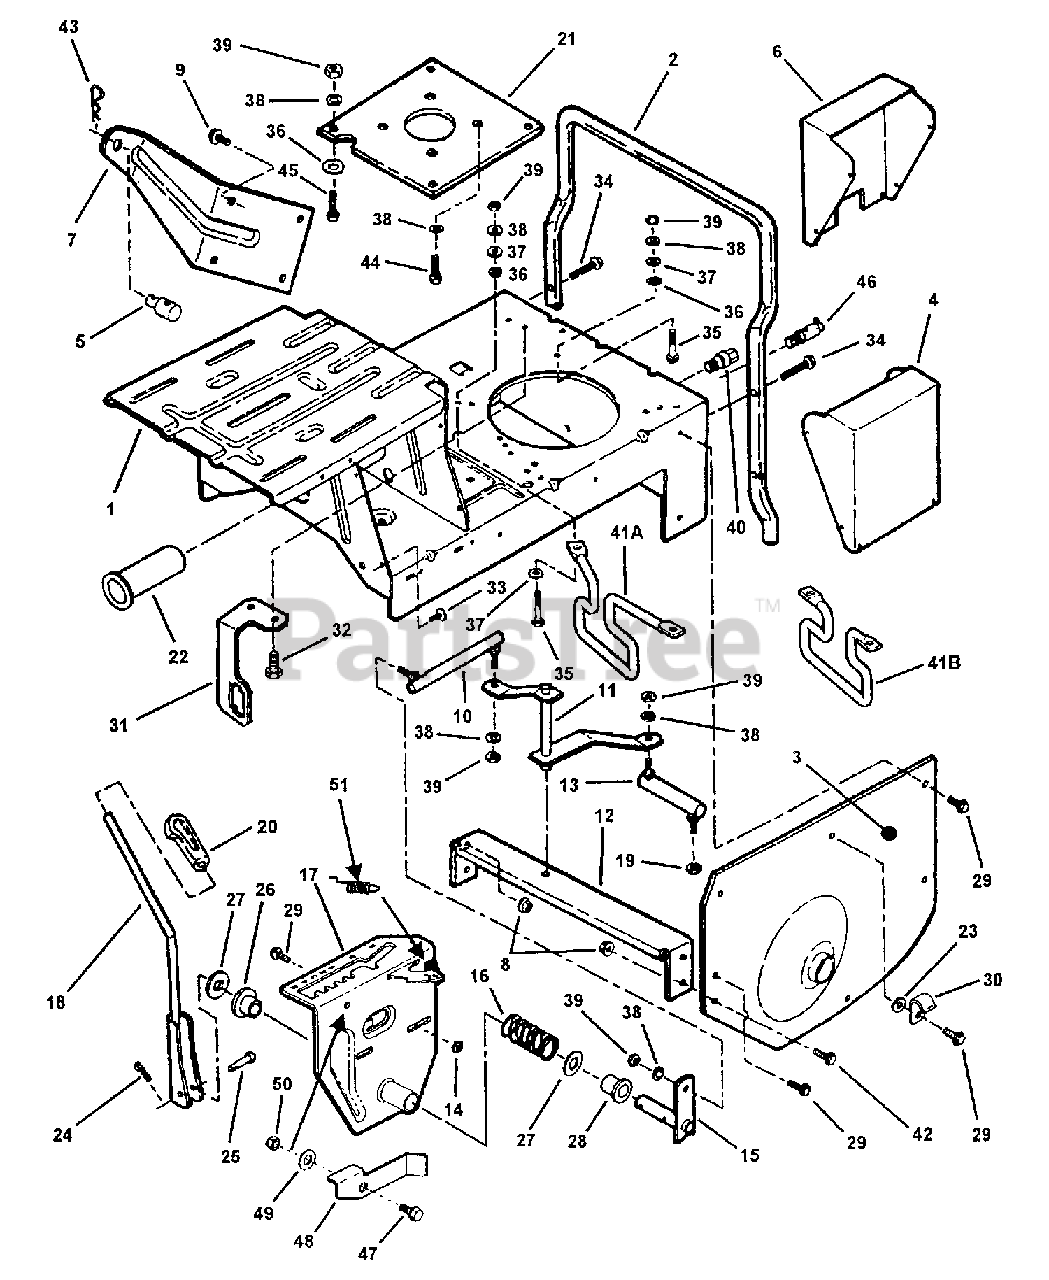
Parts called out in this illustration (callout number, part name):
1	CASE, Main (13HP)
1	CASE, Main (15HP)
2	BUMPER, Rear
3	FENDER, Left Hand
4	COVER, Battery
5	SWIVEL
6	COVER, Switch
7	WING, Rear
8	NUT, 5/16-18 Hex Flange Lock
9	SCREW, 5/16-18 x 3/4" Self-Tapping
10	LINK, Shift (Long)
11	ARM, Shift
12	BRACE, Cross
13	LINK, Shift (Short)
14	NUT, 5/16-18 Hex
15	ARM, Shift Handle
16	SPRING, Shift Handle
17	ASSEMBLY, Shift Detent
18	HANDLE, Shift
19	NUT, Hex Large Flange Lock 5/16-24
20	KNOB, Shift Handle
21	PLATE, Engine
22	BUSHING, Pilot
23	WASHER, 5/16 Internal Tooth Lock
24	COTTER-PIN, 3/32 x 3/4"
25	PIN, 1/4 x 1-3/4" Tapered Clevis
26	BUSHING, Nylon
27	WASHER, Thrust
28	BUSHING, Nylon
29	SCREW, 5/16-18 x 5/8" Self-Tapping
30	CLIP, Wire
31	BRACKET, Switch
32	SCREW, Self Tapping, 10-32 x 1/4"
33	FASTENER, 1/4x3/4 Ratchet
34	SCREW, 5/16-18 x 1-1/2" Self-Tapping
35	SCREW, 5/16-24 x 1-3/4" Hex Head Cap
36	RETAINER, 5/16 Bolt
37	WASHER, 5/16" Flat
38	WASHER, 5/16" Split Lock
39	NUT, 5/16-24 Hex
40	DRAIN, Oil (Short)
41A	GUIDE, Belt (9.48" Bolt Pattern Bent Top)
41B	GUIDE, Belt (5.74" Bolt Pattern, 5.625" Belt Gap)
42	SCREW, 5/16-18 x 3/4" Hex Cap
43	HAIRPIN, 3/32 x 1-1/2"
44	BOLT, M8-1.25 x 25mm, Self-Tap (Kohler)
45	SCREW, 5/16-24 x 1" Hex Head Cap, Grade 5
46	ASSEMBLY, Oil Valve (15HP Kohler)
47	BOLT, 5/16-18 Shoulder
48	LEVER, Over-Ride
49	WASHER, 7/16" Flat
50	NUT, 5/16-18 Nyloc
51	SPRING
